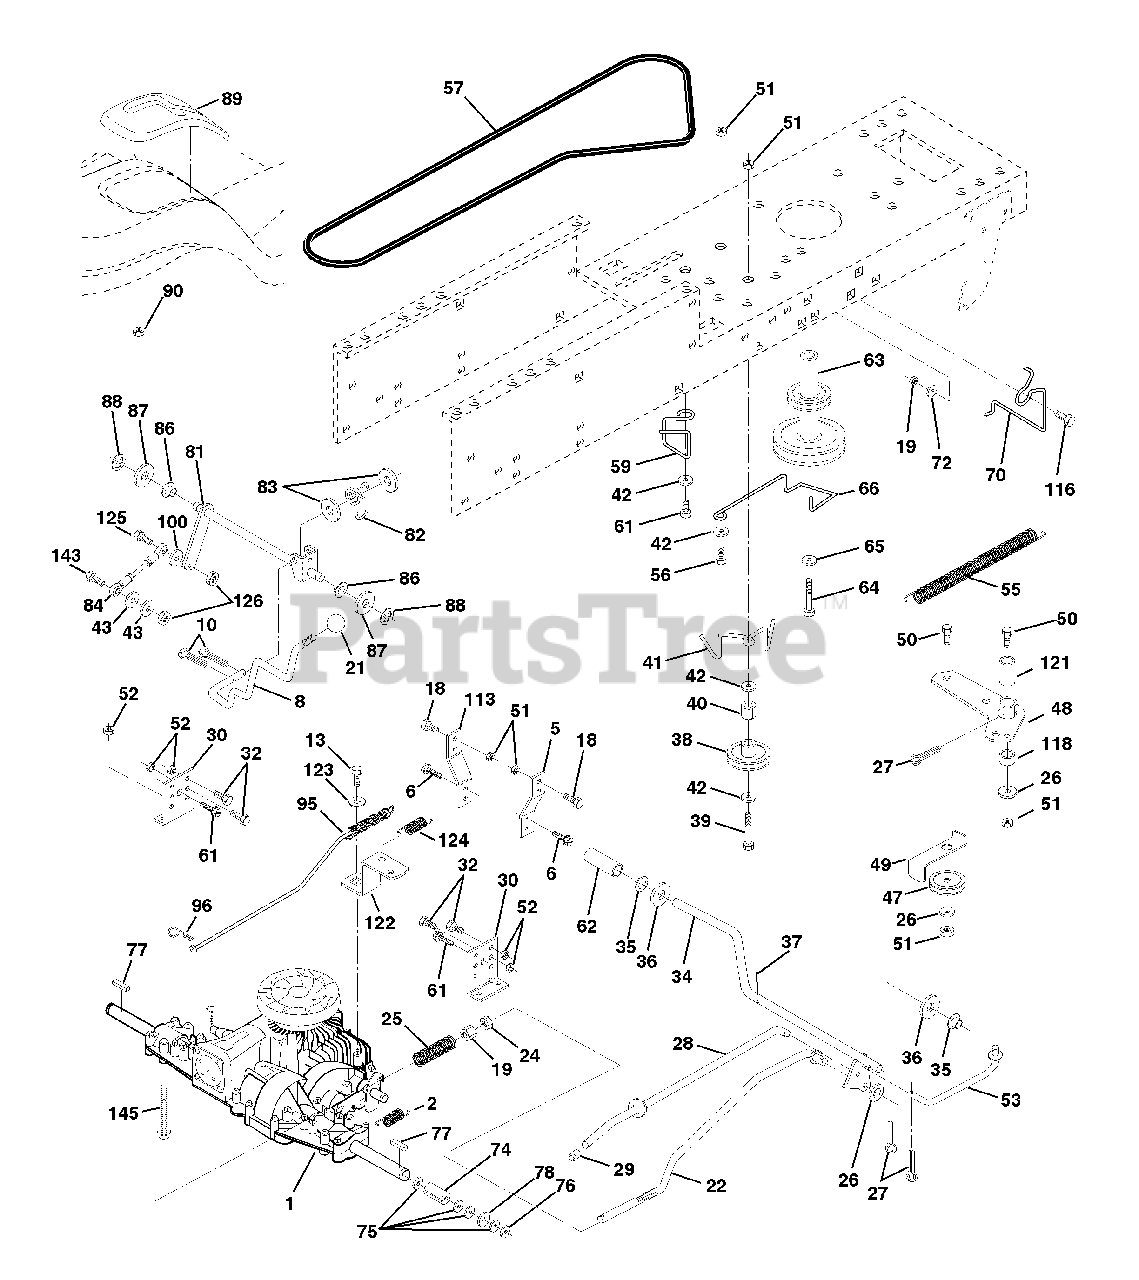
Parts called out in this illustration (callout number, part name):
1	Transaxle
2	Spring, Return Brake
5	Strap Torque
6	Screw Thdrol 5/16-18 x 3/4
8	Rod Shift Hydro STLT
10	Pin Cotter 1/8 x 1 CAD
13	Bolt 1/4-28 Unf Gr. 8 W/Patch
15	Bolt Hex Flghd 5/16-18 Gr. 5
18	Bolt Fin Hex 3/8-16 Unc x 1 Gr. 5
19	Nut Lock Hex W/Wsh 3/8-16 Unc
21	Knob, Round 1/2-13
22	Rod, Brake
24	Nut, Hex Jam 3/8-16 Unc
25	Spring, Brake Rod
26	Washer
27	Pin Cotter 1/8 x 3/4 CAD.
28	Rod, Parking Brake
29	Cap, Parking Brake
30	Bracket, Transaxle
32	Bolt Hex Hd 5/16-18 Unc x 3/4
34	Shaft, Foot Pedal
35	Bearing, Nylon
37	Pin, Roll
38	Pulley, Idler, Flat
40	Spacer, Split
41	Keeper, Belt, Idler
42	Washer 13/32 x 13/16 x 12 Gauge
43	Washer 11/32 x 5/8 x 12 Ga.
47	Pulley, Idler, V-Groove
48	Bellcrank Assembly
49	Retainer, Belt
50	Bolt
51	Nut Crownlock 3/8-16 UNC
52	Nut, Crownlock 5/16-18 Unc
53	Link, Clutch
55	Spring, Return, Clutch
56	Bolt Hex 3/8-16 x 1-1/4
57	V-Belt, Ground Drive
59	Keeper, Center Span
61	Screw Thdrol. 3/8-16 x 3/4 Ty. TT
62	Cover, Pedal
63	Pulley, Engine
64	Bolt Hex 7/16-20 X 4 Gr. 5
65	Washer
66	Keeper Belt Engine
70	Keeper Belt Engine
72	Washer 13/32 x 1-1/4 x 12 Gauge
74	Spacer, Axle PVST
75	Washer 25/32 x 1-1/4 x 16 Gauge
77	Key, Square
78	Washer 25/32 x 1-5/8 x 16 Gauge
81	Shaft Asm. Cross Hydro 18" Tires
82	Spring Torsion T/A
83	Washer 17/32 x 3/4 x 16 Ga.
84	Rod, Tie PVST 18"
86	Bushing Rod Strig. 629/632 ID
87	Washer 21/32 x 1-1/4 x 16 Ga.
88	Ring Klip #5304-62
89	Console, Shift
90	Nut Self-Thd Wsh-Thd 1/4 Zinc
95	Rod Asm Bypass PVST
96	Retainer Spring 1" Zinc/Cad
100	Washer 11/32 x 3/4 x 16 Ga.
113	Strap Torque LH LT
116	Bolt Rdhd Sq. Neck 3/8-16 x 1.25
118	Spacer Bellcrank
121	Nyliner Clutching STL
122	Plate Bypass PVST
123	Washer 9/32 x 5/8 x 16 Ga.
124	Spring Return PVST
125	Bolt Fin Hex 5/16-18 Unc x 1
126	Nut Lock 5/16-18 Unc
143	Bolt Fin Hex 5/16-18unc x 1-1/4
